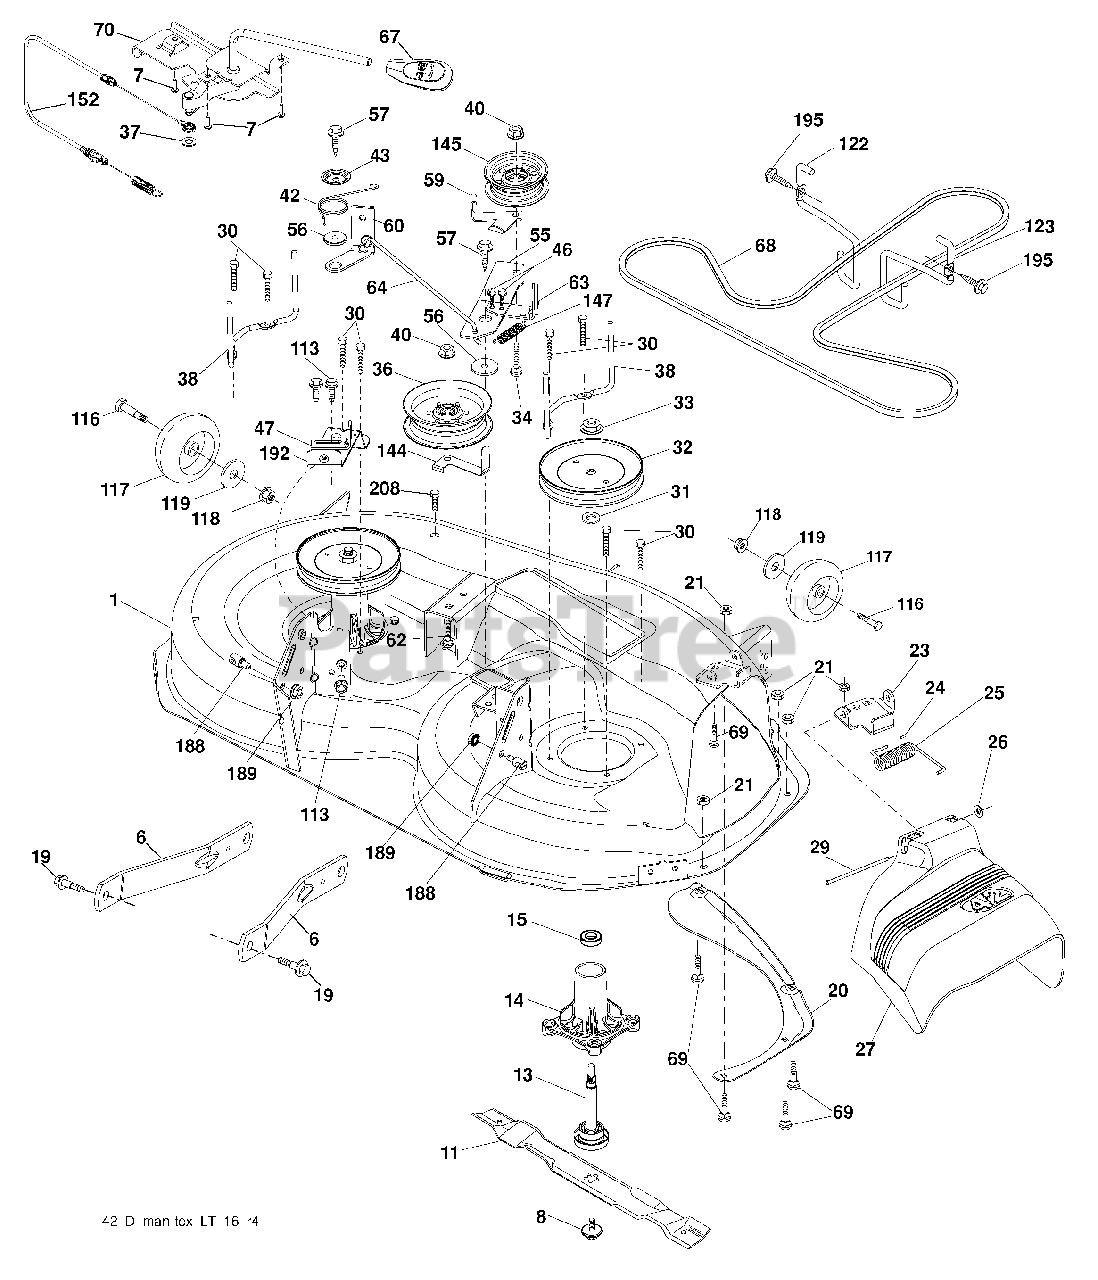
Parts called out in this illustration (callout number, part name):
1	Mower Housing
6	Arm Suspension
7	Screw #10 x 0.750 BOS Thread
8	Bolt/Washer Asm 7/16-20 unf
11	Blade, 42" Hi-Lift (For bagging or discharge)
11	Blade, 42" Mulching Premium (For better wear when mulching)
11	Blade, 42" Mulching Std (For mulching mowers only)
11	Blade 42SP" 3N1
11	Blade 42SP" Premium
13	Shaft Assembly, Mandrel
14	Housing, Mandrel
15	Bearing, Ball, Mandrel
19	Bolt, Shoulder
20	Baffle, Vortex
21	Nut, Crownlock 5/16-18 unc
23	Bracket, Deflector
24	Cap, Sleeve
25	Spring, Torsion, Deflector
26	Nut, Push
27	Shield, Deflector
29	Rod, Hinge
30	Screw Thdrol Rolling Wsh Hd
31	Washer, Spacer
32	Pulley, Mandrel
33	Nut, Toplock, Flanged
34	Bolt Carr Sh. 3/8-16 x 1-1/2 Gr. 5
36	Pulley, Idler 4.50 RAW
37	Washer 13/32 x 13/16 x 16 Ga.
38	Keeper Belt LH Mandrel
40	Nut, Lock Flg. 3/8-16 unc
42	Spring Torsion Brake
43	Spring Torsion Retainer
46	Screw Thd Roll 1/4-20 x 5/8
47	Bracket Clutch Cable
55	Arm, Idler
56	Spacer, Retainer
57	Screw Hexwsh Thd 3/8-16 x 1
59	Guard, Tuv Idler (94)
60	Arm Brake Mower
62	Bolt Rdhd Sqnk 3/8-16 unc x 2
63	Arm Brake Mower
64	Linkage Brake
67	Handle, Clutch Cable
68	V-Belt
69	Bolt Rdhd Sqnk 5/16-18 x 5/8
70	Clutch Asm. Manual
113	Screw 5/16-18
116	Bolt Shoulder "A" 2.41 "B" 1.66
117	Wheel Gage
118	Nut Centerlock 3/8-16 unc
119	Washer 3/8 x 7/8 x 14 Ga.
122	Keeper Belt Eng. LH
123	Keeper Belt Eng. RH
144	Keeper Belt
145	Pulley Idler Primary
147	Spring Return
152	Cable Clutch Manual w/Spr.
188	Stud Fastener
189	Nut Lock Hex Flange
192	Bracket Brake Stand LH
195	Screw Hexwsh Thdr 3/8-16 x 3/4
208	Screw THDROL 3/8-16 x 1/2
208	Mandrel Assembly
208	Replacement Mower, Complete
